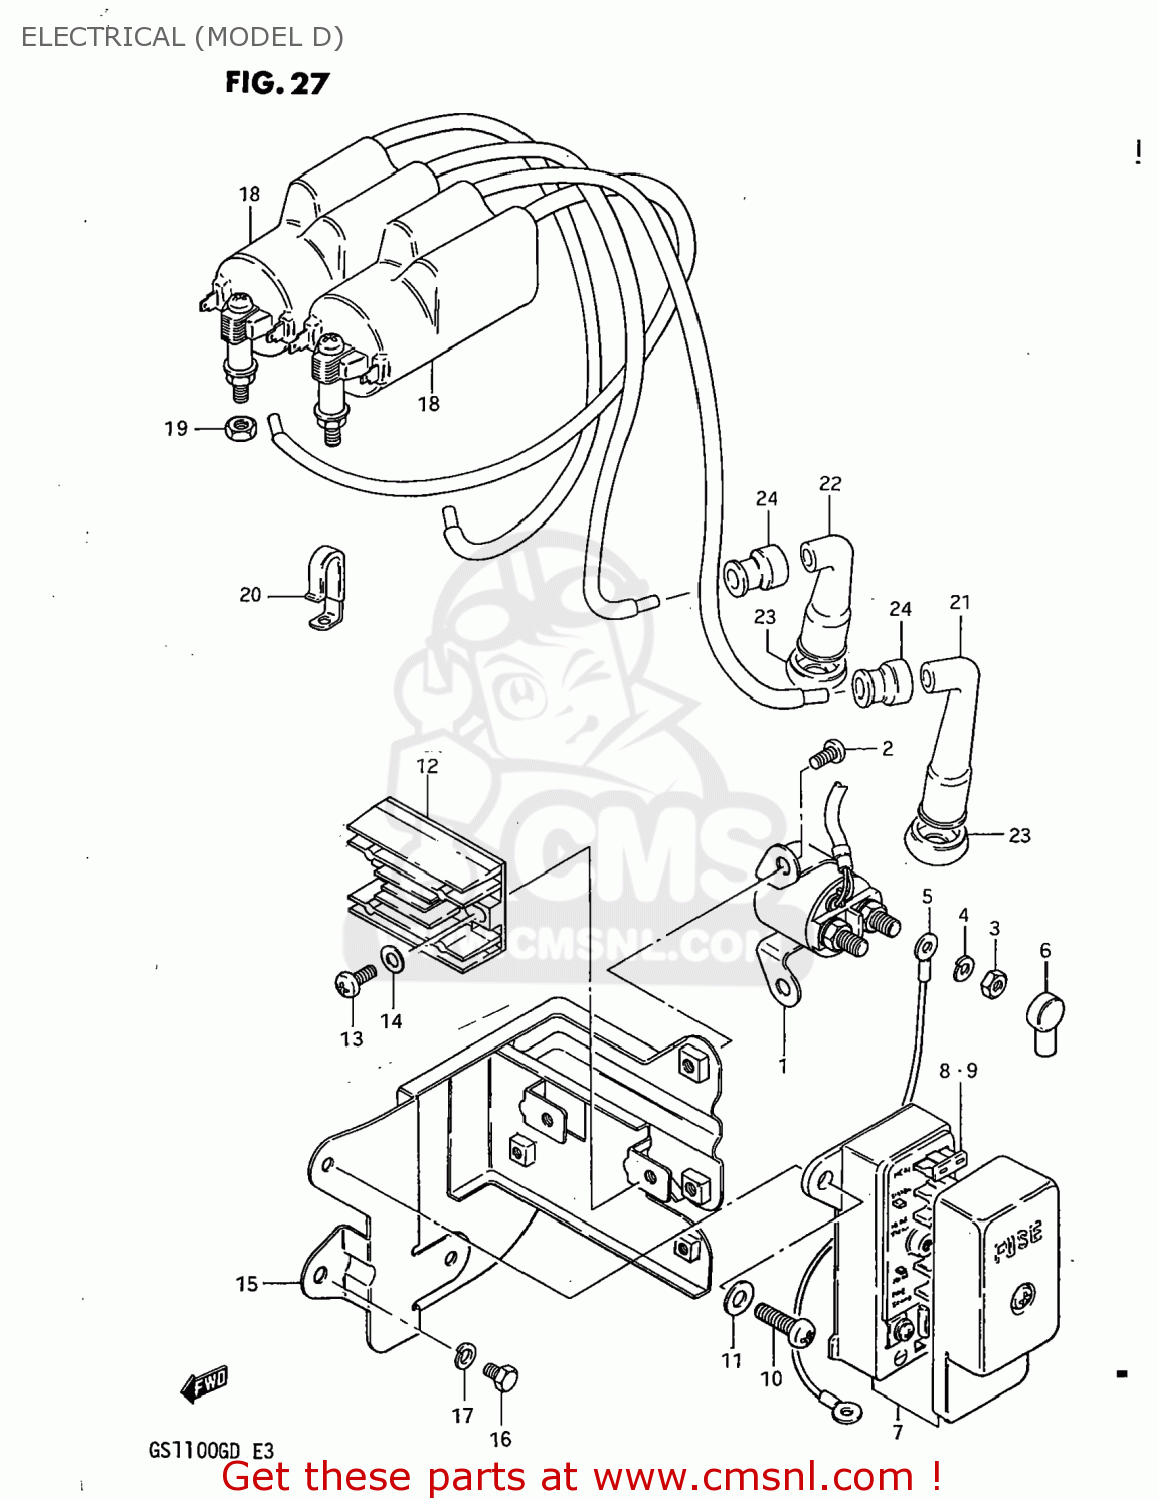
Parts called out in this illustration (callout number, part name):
1	RELAY ASSEMBLY,STARTING MOTOR
2	SCREW(6X10)
3	NUT 6MM
4	LOCK WASHER
5	CABLE,STARTING MOTOR
6	CAP,STARTER RELAY
7	BOX ASSEMBLY,FUSE
8	FUSE(10A)
9	FUSE(15A)
10	SCREW 6X12
11	WASHER
12	RECTIFIER ASSEMBLY
13	SCREW
14	WASHER
15	HOLDER COMP,ELECTRONIC PARTS
16	BOLT
17	LOCK WASHER
18	COIL ASSEMBLY,IGNITION
19	NUT
20	CLAMP
21	CAP ASSY,SPARK PLUG
22	CAP,SPARK PLUG
23	SEAL,SPARK PLUG
24	SEAL,SPARK PLU
